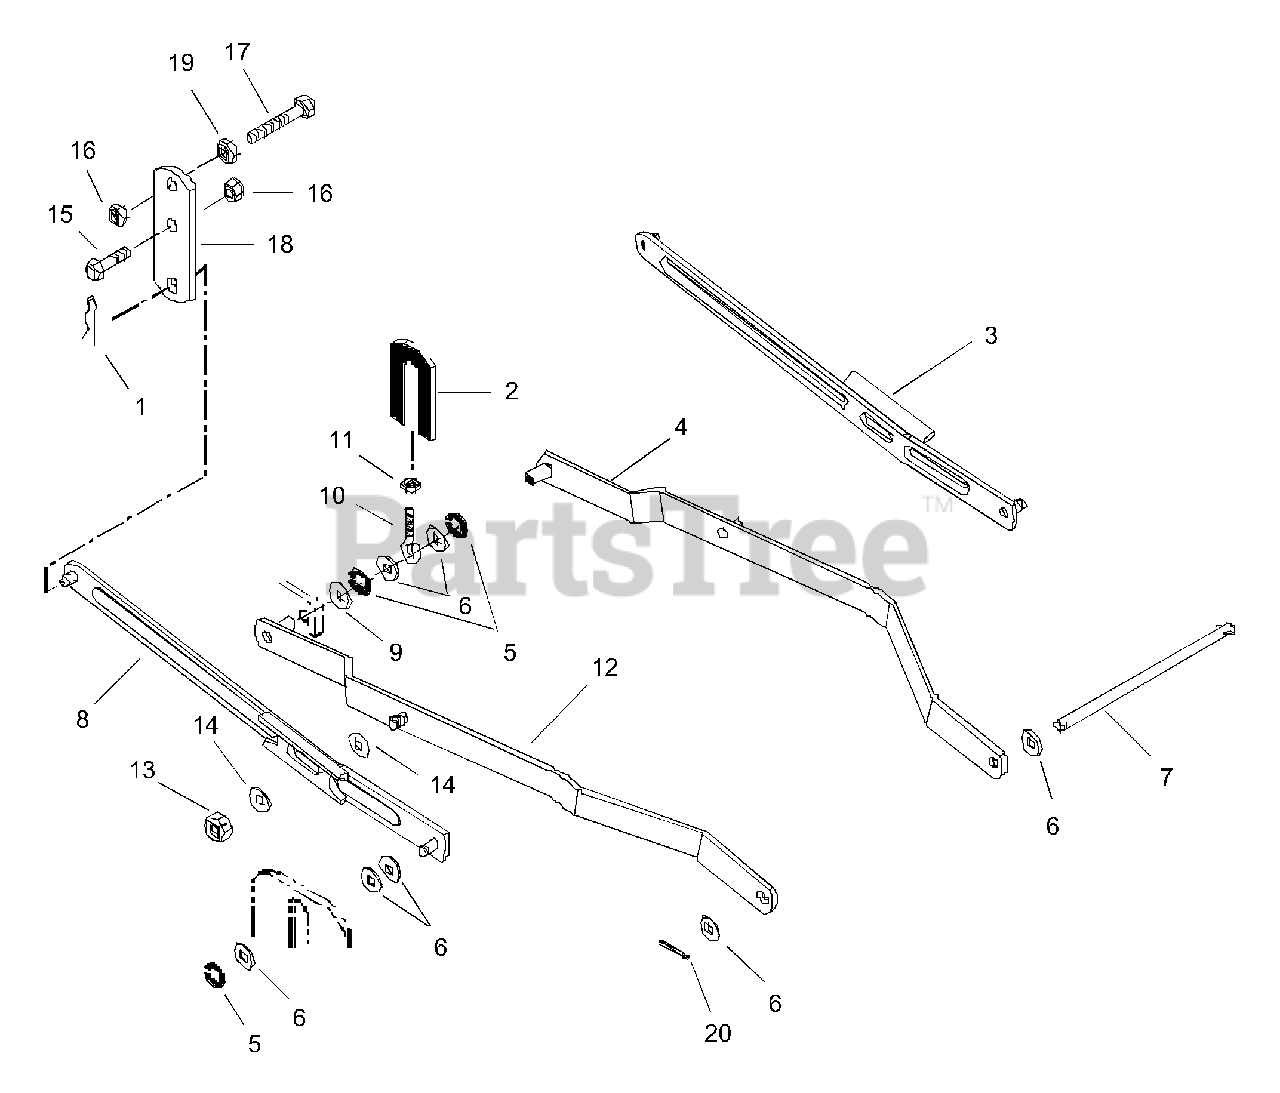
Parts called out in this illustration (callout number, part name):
1	Pin-Hair-External .12 x .31 x 2.37
2	Adjuster Link
3	Rear Hanger, Left Hand
4	Left Hand Lift Arm
5	Ring-Retaining-External .500 x .050
6	Washer-Flat-Steel .531 x 1.062 x .095
8	Rear Hanger, Right Hand
9	Washer-Flat-Steel .531 x 1.062 x .095
11	Nut-Jam .375-16
12	Right Hand Lift Arm
13	Nut-Locking-Center .625-11
14	Washer-Flat-Steel .656 x 1.312 x .095
15	Bolt-Hex .38-16 x .75 Grade 5
16	Nut-Locking-Center .375-16
17	Bolt-Hex .38-16 x 1.75 Grade 5
18	Hanger Bracket
19	Nut-Hex .375-16
20	Pin-Cotter .12 x 1.0
